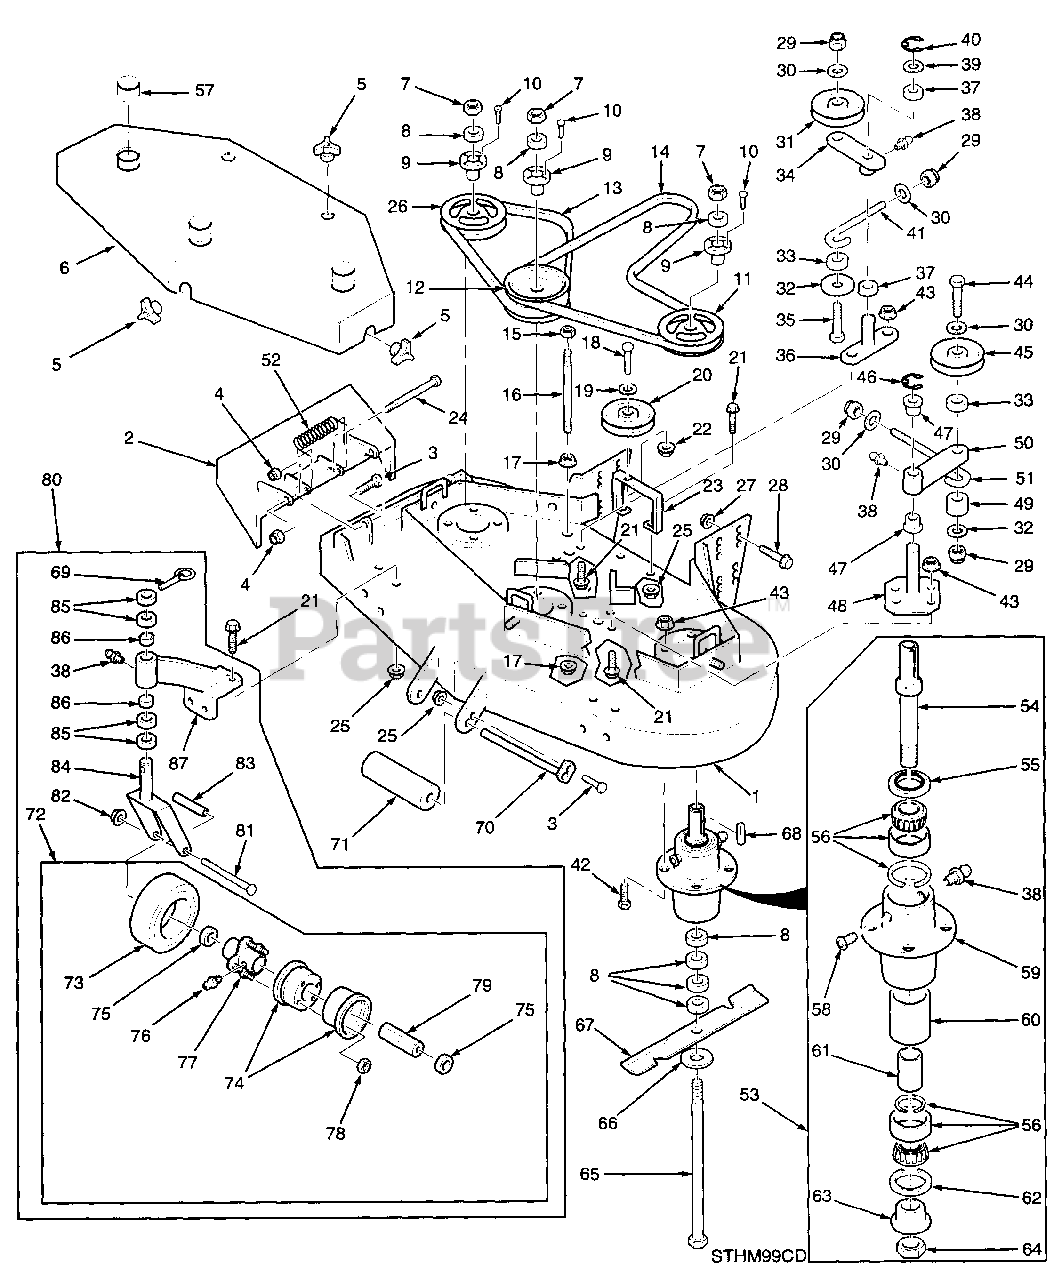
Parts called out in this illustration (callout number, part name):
1	Cutter Deck
2	Discharge Chute
3	Bolt, 5/16-18 x 1" Hex Head
4	Nut, 5/16-18 Elastic Stop
5	Wing Nut, 3/8-16
6	Belt Cover
7	Nut, 5/8-11 Hex Head
8	Spacer, Cutter Blade
9	Tapered Hub, 1.125 Bore
10	Bolt, 1/4-20 x 3/4 Hex Head
11	Pulley, 6.35 O.D.
12	Pulley, Double Groove, 6.35/5.75 O.D.
13	Belt, R.H. Blade Drive
14	Belt, Deck Drive
15	Lock Nut, 3/8-16 Hex Head
16	Stud, 3/8-16 x 6-3/4"
17	Nut, 3/8-16 Serr. Flange
18	Bolt, 3/8-16 x 2-1/4"
19	Flatwasher, 3/8 (.391 x.938 x .105)
20	Pulley, Belt Guide
21	Capscrew, 5/16-18 x 3/4 Ser. Flg. HH
22	Nut, 3/8-16 Elastic Stop
23	Idler Pulley Support
24	Bolt, Hex Head 5/16-18 x 4-1/4"
25	Nut, 5/16-18 Ser. Flg. Hex Hd.
26	Pulley, 5.75
27	Nut, 1/2-13 Ser. Flg. Hex Hd.
28	Capscrew, 1/2-13 x 1-1/4 Ser. Flg.
29	Nut, 3/8-16 Elastic Stop
30	Flatwasher, 3/8 (.391 x .938 x .105)
31	Pulley
32	Flatwasher, 3/8 (.375 x 1.50 x .060)
33	Spacer
34	Idler Arm
35	Bolt, 3/8-16 x 2-1/4"
36	Idler Pivot
37	Bushing, Bronze Oilite-3/4 ID
38	Grease Fitting, Str. 1/4-28 Self Tap.
39	Flatwasher, 3/4 (.776 x 1.25 x .059)
40	Retaining Ring, .75 EXT 'E'
41	J-Rod idler Pulley
42	Bolt, 5/16-18 x 1-1/4" Hex Head
43	Nut, 5/16-18 Ser. Flange
44	Bolt, 3/8-16 x 3-1/2" Hex Head
45	Pulley, Deck Drive Idler
46	Retaining Ring, 1-1/8 EXT 'E'
47	Bushing, Bronze Oilite - 1-1/8 ID
48	Idler Pivot Support
49	Spacer
50	Idler Arm
51	J-Rod, Drive Idler
52	Spring, Chute Return
53	Spindle Assembly
54	Shaft, Cutter Spindle
55	Seal, 2.00 O.D. x 1.50 Bore
56	Bearing Assembly
57	Shield, Spindle
58	Relief Fitting, Cutter Spindle
59	Spindle Housing
60	Spacer, Outside
61	Spacer, Inside
62	Seal, 2.00 O.D. x 1-5/8 Bore
63	Spindle Bushing Bottom
64	Nut, 1-1/16-18 UNEF-2B
65	Bolt, 5/8-11 x 9-1/2"
66	Flatwasher, 5/8 (.688 x 1.75 x .134)
67	Cutter Blade, 21" Standard
68	Key, 1/4 x 1/4 x 2"
69	Quick Pin
70	Shaft, Roller
71	Guide, Roller
72	Wheel Assy., Caster
73	Tire Only, Caster Wheel
74	Rim Pair, Caster Wheel
75	Retainer, Caster Wheel
76	Grease Fitting, 45 Deg. 1/4-28
77	Hub Assy. W/Bolts, Caster Wheel
78	Tapered Hex Nut, 5/16-18
79	Roller Bearing, Caster Wheel
80	Caster Wheel Assembly
81	Bolt, 1/2-13 x 5-1/2" Hex Head
82	Nut, 1/2-13 Elastic Stop
83	Sleeve, Caster Wheel Bearing
84	Caster Yoke
85	Spacer, Caster Yoke 1/2"
86	Bushing, 7/8 x 1" Flanged
87	Support Assembly
